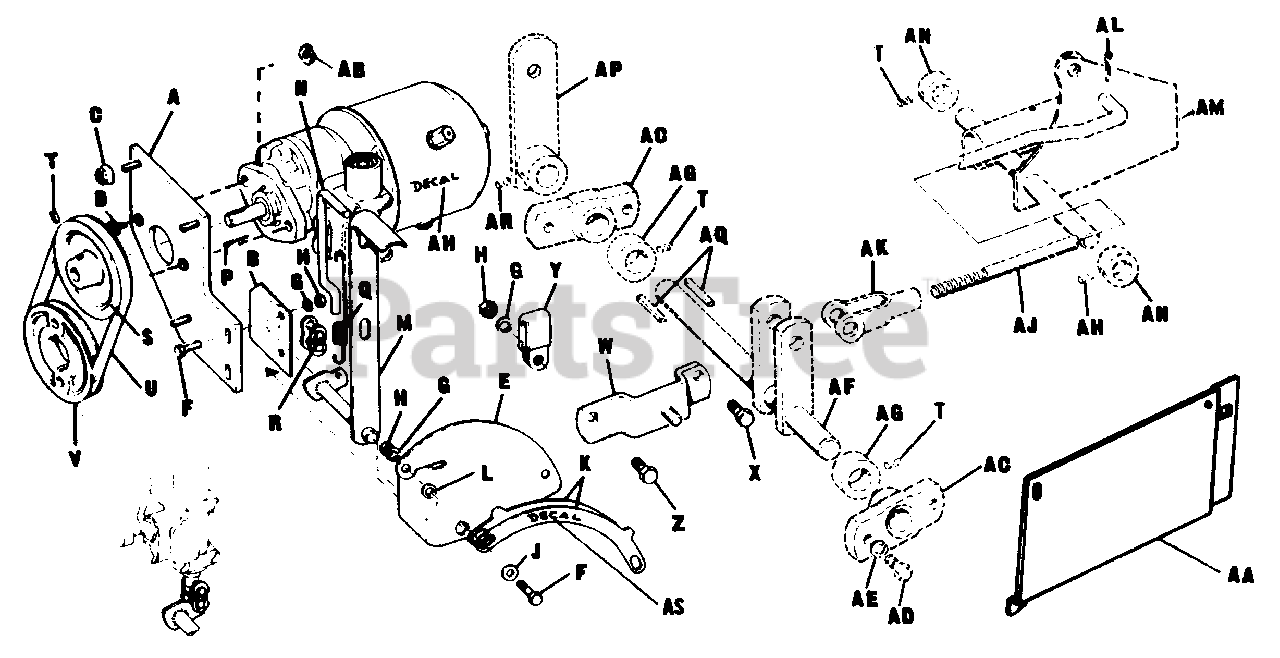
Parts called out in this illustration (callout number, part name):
A	Pump Support Assembly
B	Angle Bracket
C	Hex. Nut, Whiz Lock, 5/16"-18
D	Machine Screw, Flat Hd. 3/8-16 x 1-1/4" lg.
F	Hex. Cap Screw, 1/4"-20 x 3/4"
G	Lock Washer, 1/4"
H	Full Hex. Nut, 1/4"-20
J	Plain Washer, 1/4"
K	Stop Plate
M	Lever Assembly
N	Latch Rod
P	Cotter Pin, 3/32" x 5/8"
R	Connecting Link
S	Pump Pulley
T	Set Screw, 5/16"-18 x 5/16"
V	Drive Pulley
W	Pivot Bar Assembly
X	Hex. Cap Screw, 5/16"-18 x 1"
Y	Hose Clamp
Z	Hex Cap Screw, 1/4"-20 x 1"
AA	Panel, Side L.H.
AB	Nut, Whiz-Lock Flange 3/8"-16
AC	Lift Lever Bearing
AD	Hex. Cap Screw, 3/8"-16 x 7/8"
AE	Lock Washer, 3/8"
AF	Lift Shaft Assembly
AG	Set Collar
AK	Adj. Yoke End
AL	Cotter Pin, 1/8" Dia. x 1"
AM	Tiller Lift Assembly
AN	Set Collar
AP	Front Lift Lever Assembly
AR	Set Screw, 5/16"-18 x 1/4"
